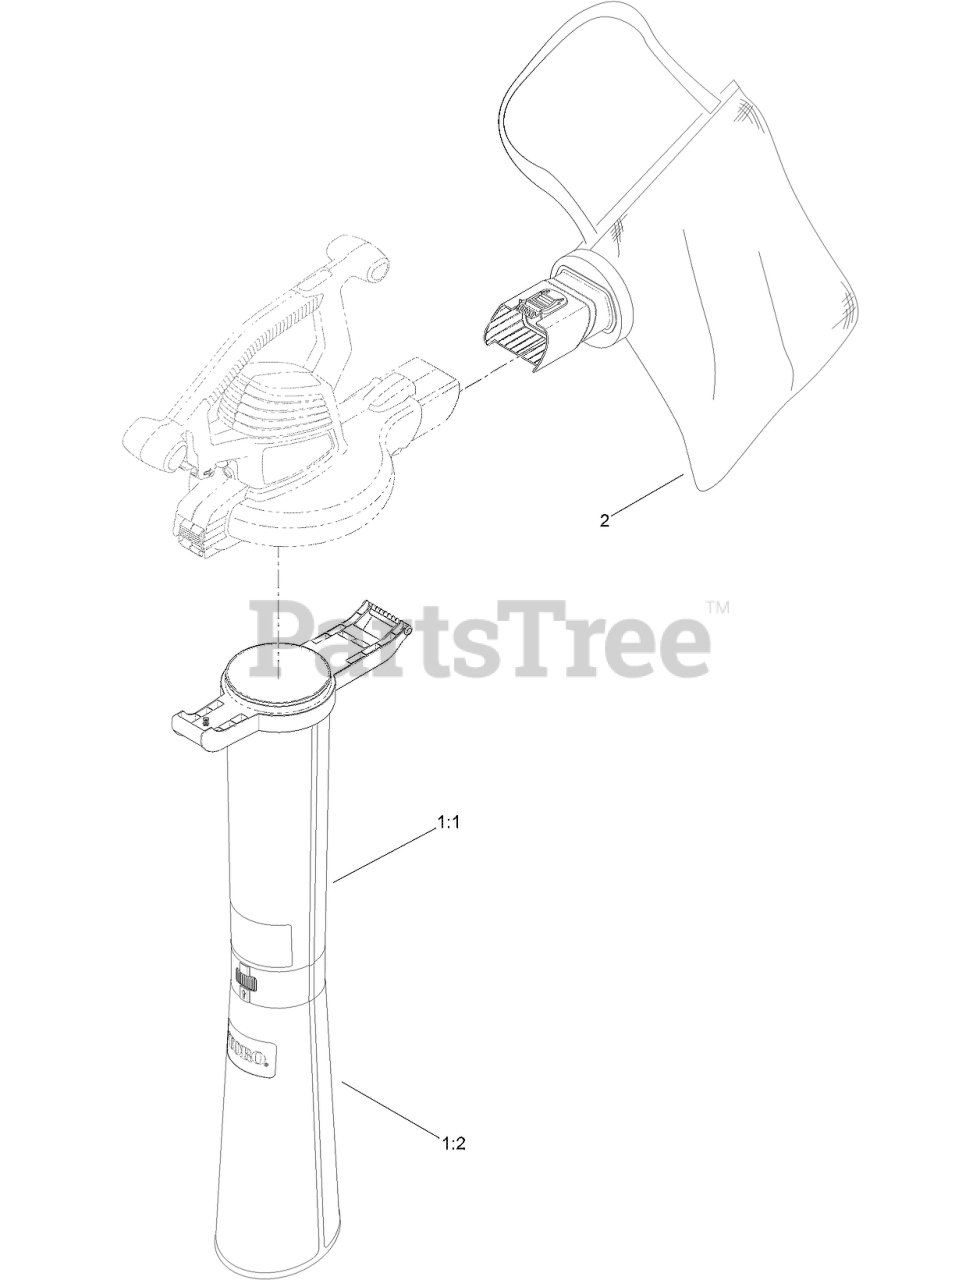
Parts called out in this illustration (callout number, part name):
1:1	TUBE-VACUUM, UPPER
1:2	TUBE-VACUUM, LOWER
2	BAG ASM
